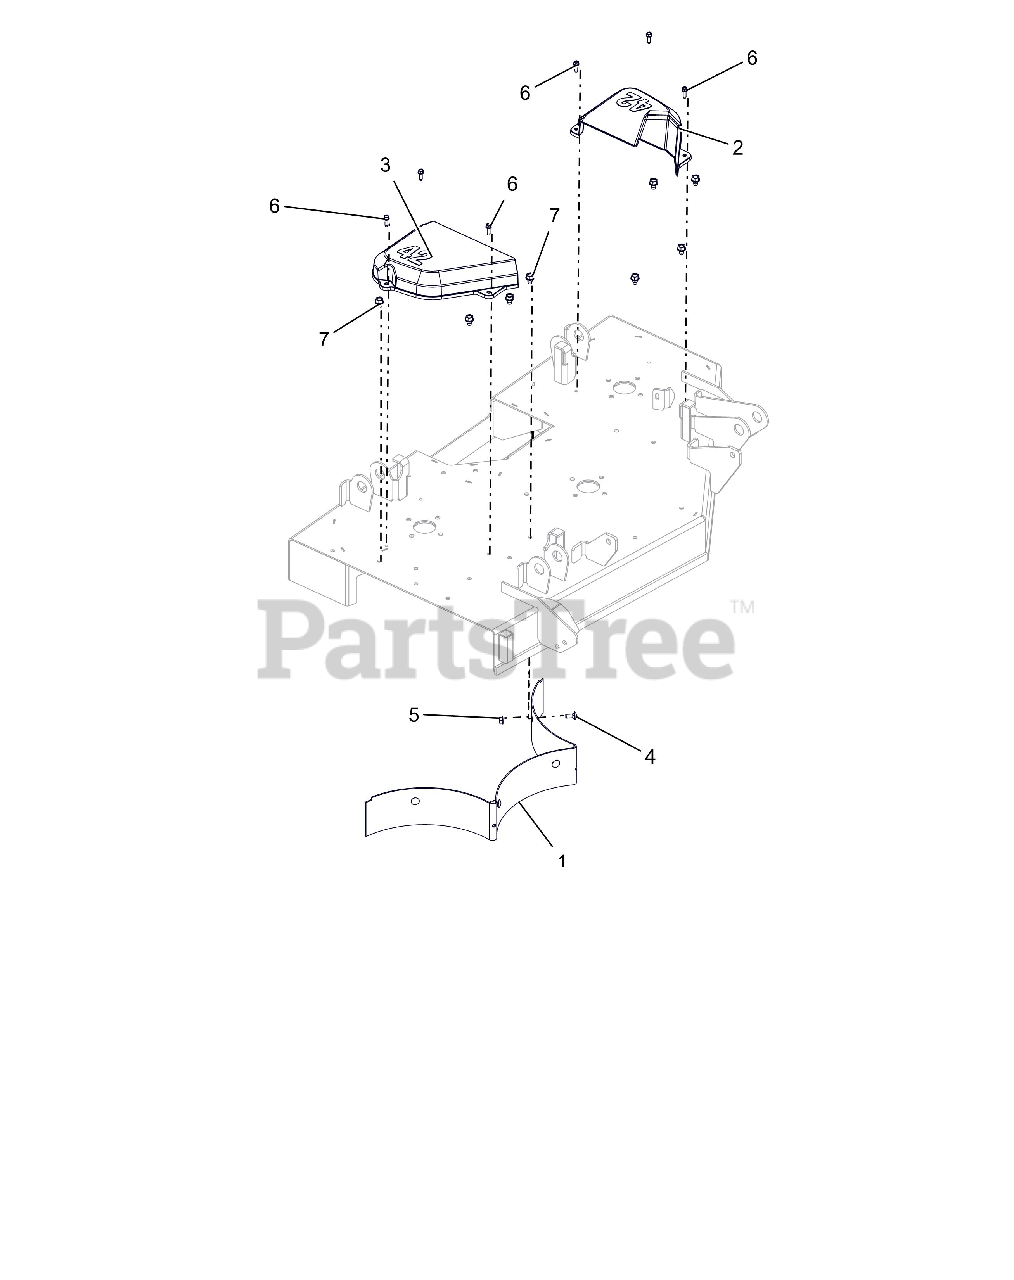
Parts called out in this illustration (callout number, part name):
1	BAFFLE, REAR 42
2	COVER, BELT 42" LH
3	COVER, BELT 42" RH
4	@BLT-RDHDSQNK .31-18X.75 G5YZ
5	@NUT-LK-TOP-FLG .31-18 YWZC
6	SCR-TAP-PM .25-20X.75 TR YWZ
7	@SCR-TAP .38-16X.50 HWH TR YWZ
